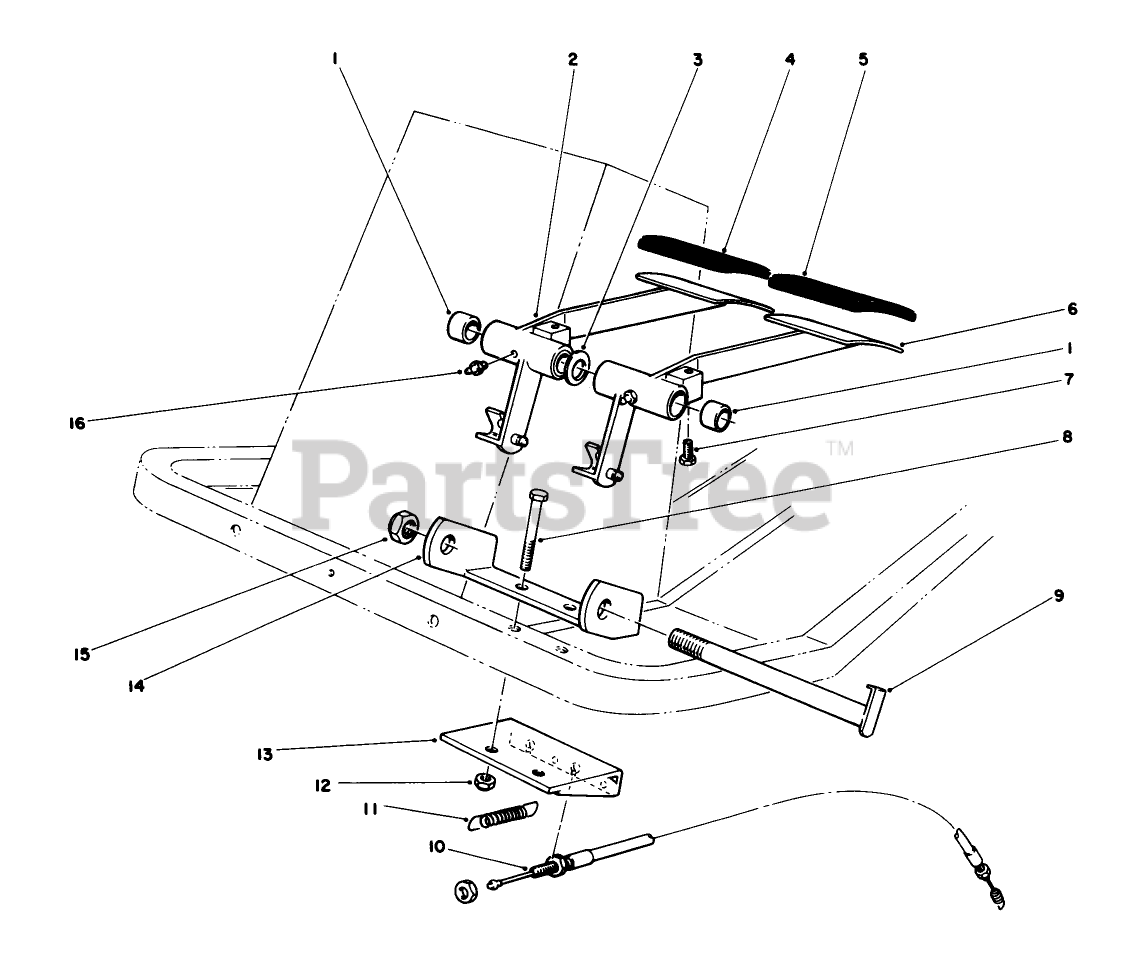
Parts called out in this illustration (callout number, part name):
1	BUSHING
3	WASHER-FLAT
7	BOLT 60183
8	SCREW-HH
11	EXTENSION SPRING *O
12	NUT-LOCK, NI
13	CABLE BRKT WA *R
15	NUT-LOCK, NI
16	FITTING-GREASE
